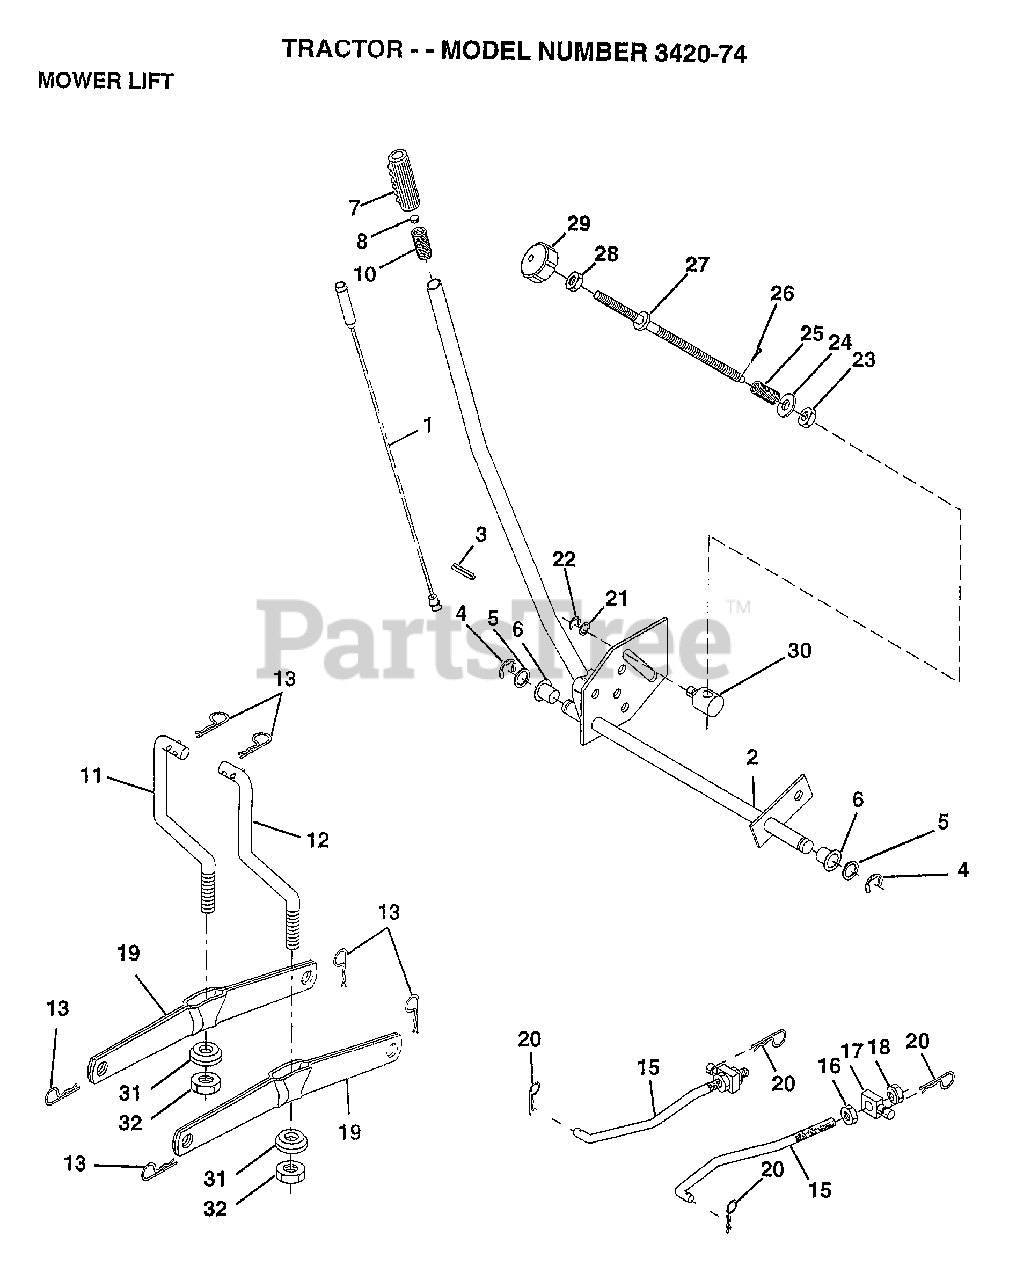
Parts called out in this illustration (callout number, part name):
1	WIRE ASM
2	SHAFT.ASM.LIFT
3	PIN GROOVE
5	WASHER
6	NYLON BEARING
7	GRIP
15	LINK.FRONT
16	NUT
17	TRUNION
18	NUT.LK.W/WSH.1/2.
19	ARM SUSP REAR
20	RETAINER.SPRING
23	NUT T
24	WASHER
25	SPRING.COMP.INF.H
27	ROD.ADJ.LIFT
28	NUT
29	KNOB INF 3/8-16
30	TRUNNION
31	BEARING PVT LH
32	NUT.CROWNLOCK.3/8
49	NUT.HXFLG.LOCK.
50	NUT PUSH M
